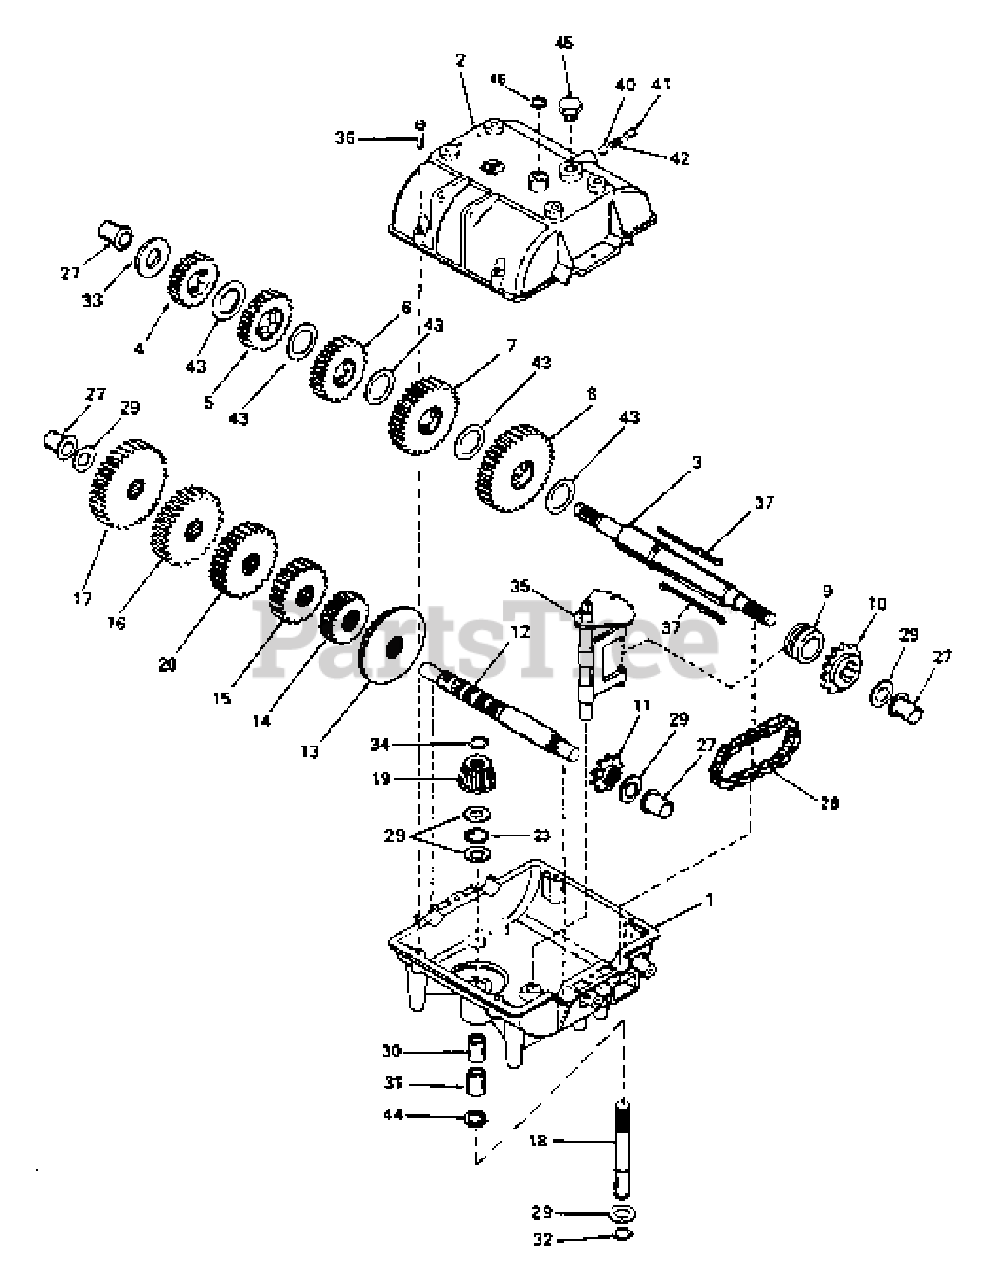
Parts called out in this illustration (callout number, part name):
1	TRANSMISSION CASE
2	TRANSMISSION COVER
3	OUTPUT & BRAKE SHAFT
4	SPUR GEAR (27 TEETH)
5	SPUR GEAR (30 TEETH)
6	SPUR GEAR (32 TEETH)
7	SPUR GEAR (35 TEETH)
8	SPUR GEAR (37 TEETH)
9	SHIFT COLLAR
10	SPROCKET (18 TEETH)
11	SPROCKET (9 TEETH)
12	COUNTERSHAFT
13	BEVEL GEAR (42 TEETH)
14	SPUR GEAR (12 TEETH)
15	SPUR GEAR (15 TEETH)
16	SPUR GEAR (20 TEETH)
17	SPUR GEAR (23 TEETH)
18	INPUT SHAFT
19	INPUT BEVEL PINION
20	SPUR GEAR (18 TEETH)
23	THRUST BEARING
27	FLANGED BUSHING
28	ROLLER CHAIN (NO.41 CHAIN, 24 LINKS)
29	THRUST WASHER
30	NEEDLE BEARING
31	NEEDLE BEARING
32	RETAINING RING
33	THRUST WASHER
34	RETAINING RING
35	SHIFT ROD & FORK
36	SCREW, FLANGED HEX HD. THREADFORMING 1/4-20 X 1-1/4"
40	STEEL BALL, 5/16"
41	SET SCREW, 3/8-16 X 3/8"
43	THRUST WASHER
45	THREADED PLUG
46	SQUARE CUT SEAL
47	COMPLETE TRANSMISSION
